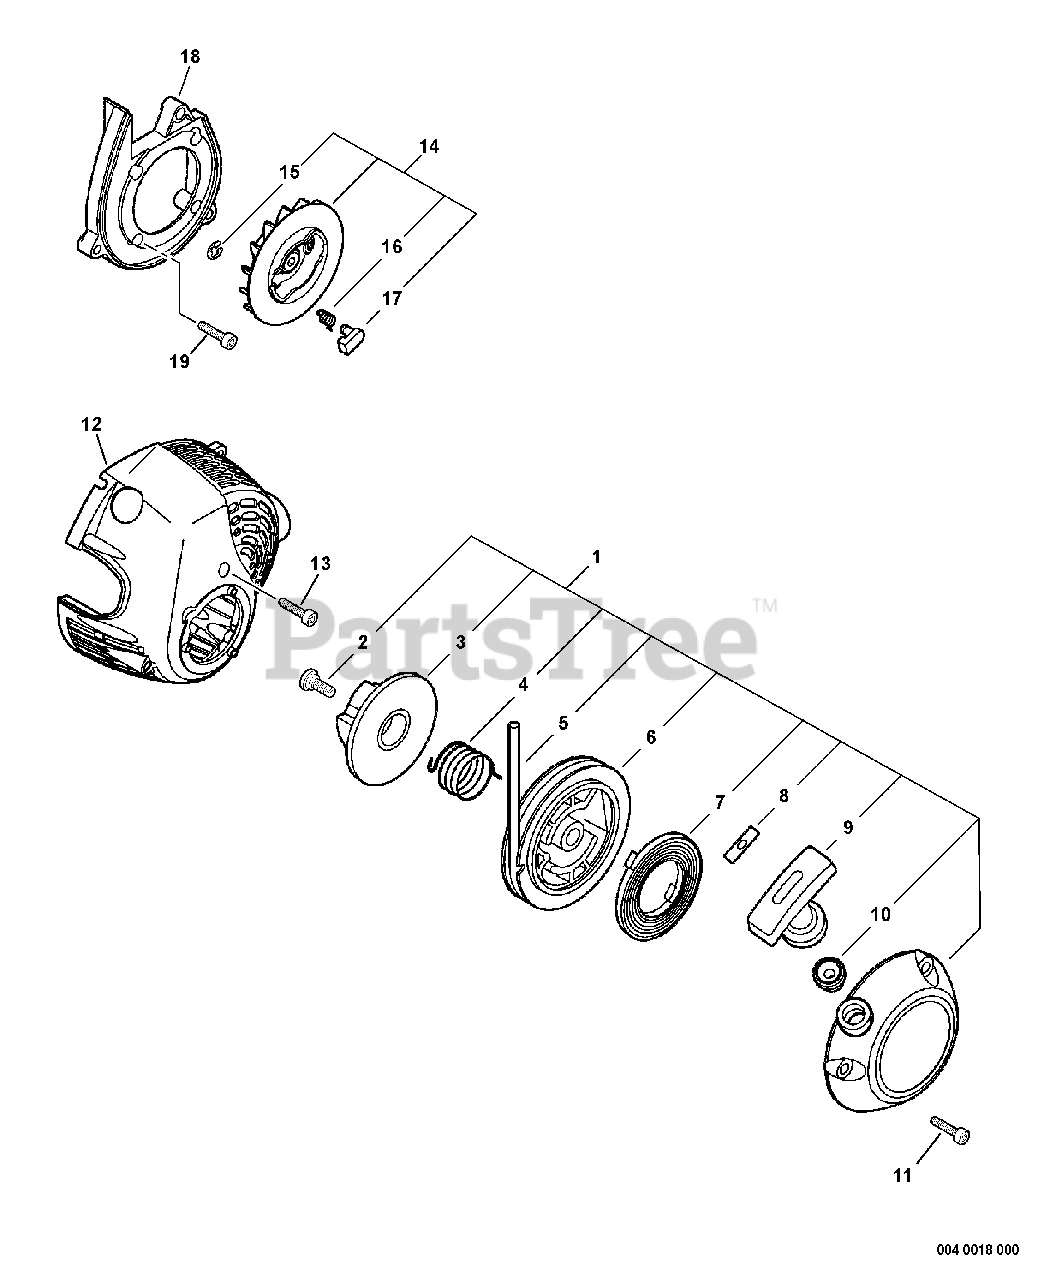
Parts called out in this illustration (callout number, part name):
1	STARTER ASSY
2	SCREW
3	PLATE, CAM
4	SPRING, DAMPER
5	ROPE, STARTER - 3X700
6	REEL, ROPE
7	SPRING, REWIND
8	RETAINER, ROPE
9	GRIP, STARTER
10	GUIDE, ROPE
11	SCREW - 5X16
12	COVER, ENGINE
13	SCREW - 5X20 -- TAPPING
14	STARTER PAWL ASSY
15	RING, RETAINING - 4
16	SPRING, RETURN
17	PAWL, STARTER
19	SCREW - 4X16
